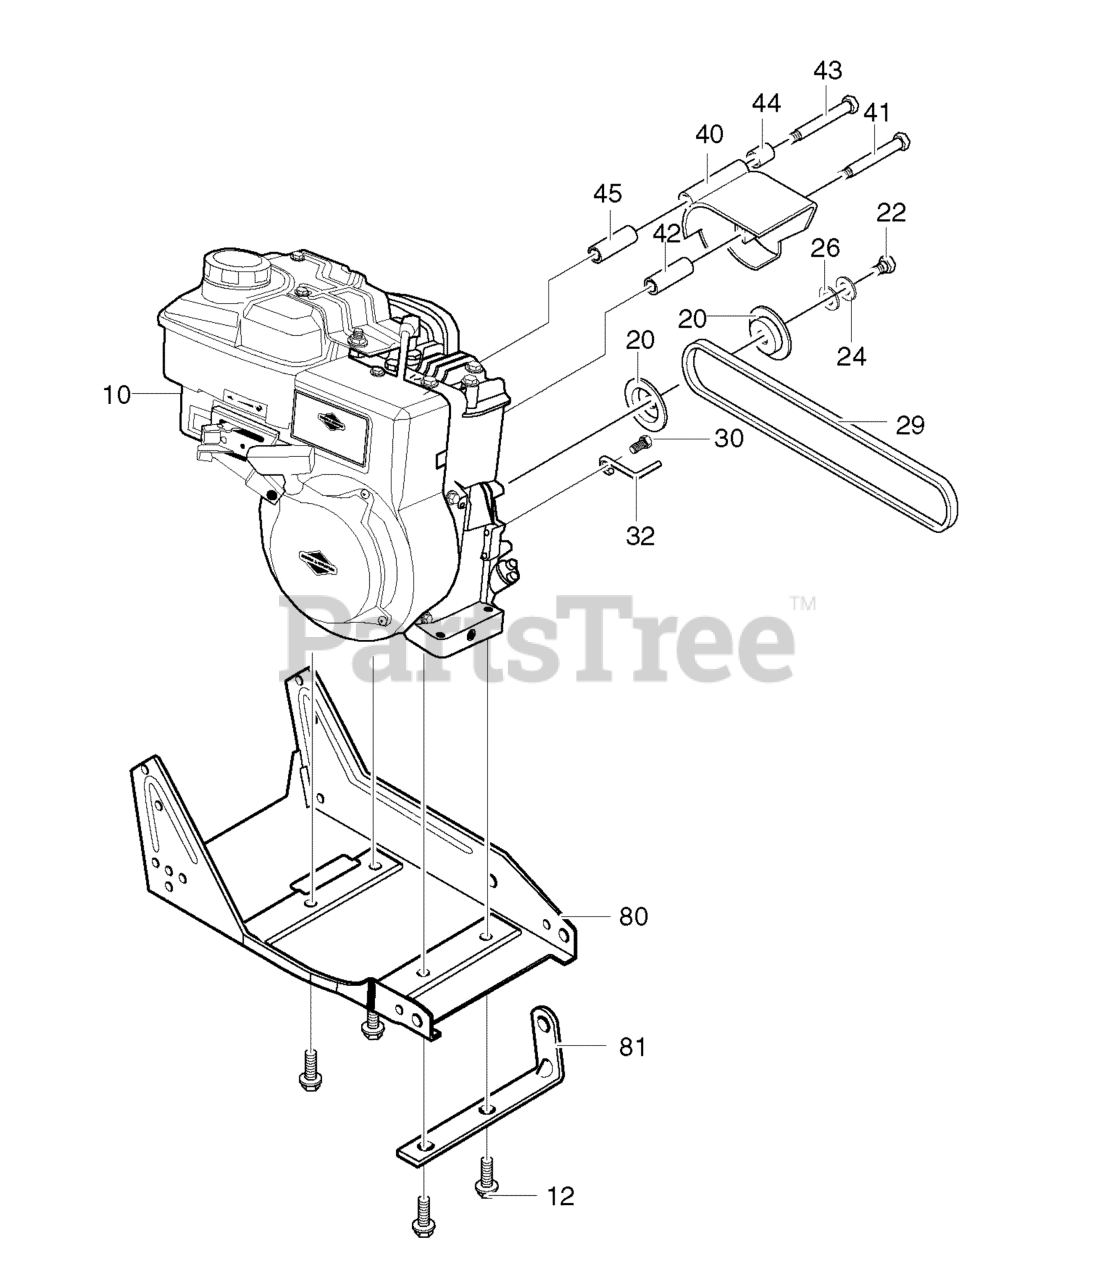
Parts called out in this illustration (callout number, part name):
10	Engine
12	Screw, 3/8-16 x 1.00
20	Pulley, Half
22	SCREW, 5/16-24 x 1.00
26	Flatwasher
29	Belt, V4L 32.60LG
30	Screw and Washer Assembly
32	Guide, Belt
40	Cover, Engine Pulley
41	Screw, 5/16-24 x 3.00
42	Spacer, Sleeve
43	Screw, 5/16-24 x 3.75
45	Spacer, Sleeve
80	Frame, Assembly Edger
